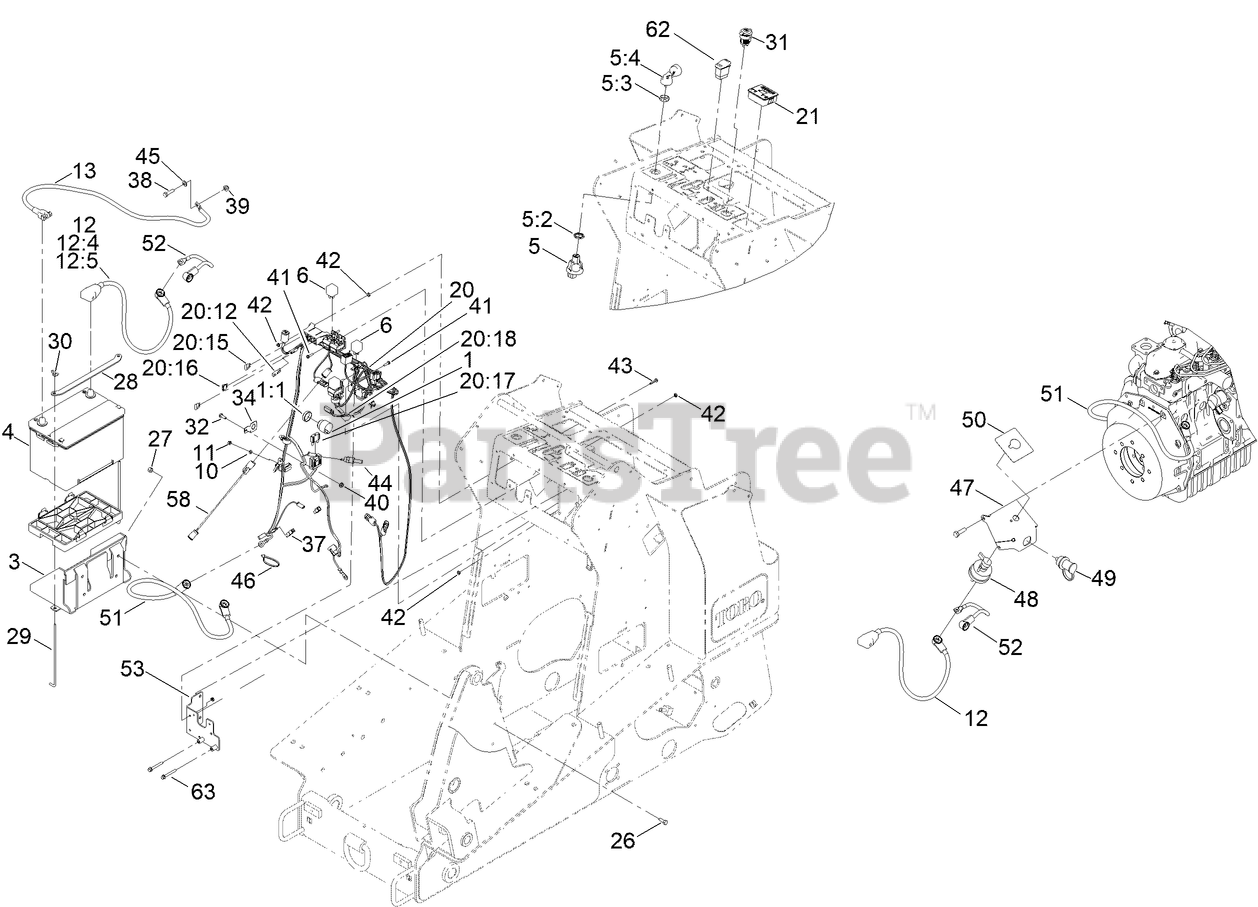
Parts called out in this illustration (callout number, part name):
1	AUDIO ALARM ASM
1:1	NUT-PLASTIC, KNURLED
3	TRAY-BATTERY
4	BATTERY
5	IGNITION SWITCH ASM
5:2	NUT-HEX
5:3	NUT-FACE
5:4	SET-KEY, IGNITION
10	WASHER-LOCK, SPRING
11	NUT-HEX
12	CABLE-BATTERY, POS ASM
12:4	BOLT-BATTERY CLAMP, 5/16-18 UNC
12:5	NUT-CLAMP, BATTERY
13	CABLE-NEGATIVE
20	HARNESS-WIRE, TX1000
20:15	FUSE-BLADE, 10 AMP
20:16	FUSE-BLADE, 15 AMP
20:17	FUSE-BLADE, 50 AMP
20:18	CAP-PLUG
21	MODULE-HOUR METER
26	SCREW-HH
27	NUT-LOCK, NI
28	STRAP-HOLD DOWN, BATTERY
29	ROD-HOLD DOWN, BATTERY
30	NUT-WING
31	RECEPTACLE-12V
32	SCREW-HH
34	CLIP-FUSE
37	HARNESS-LINK, FUSIBLE
38	SCREW-HH
39	NUT-HF, NI
40	NUT-HF
41	SCREW-HWH
42	NUT-KEPS
43	SCREW-HWHTF
44	SWITCH-TEMP
45	WASHER-PLAIN
46	TIE-CABLE
47	MOUNT-REMOTE TERMINAL
48	SWITCH-DISCONNECT, MASTER
49	STUD-JUMPER, POSITIVE
50	DECAL-BATTERY DISCONNECT
51	CABLE-BATTERY, POSITIVE
52	CABLE-BATTERY, POSITIVE
58	HARNESS-WIRE
62	SWITCH-INTERMITTENT
63	SCREW-HHF
